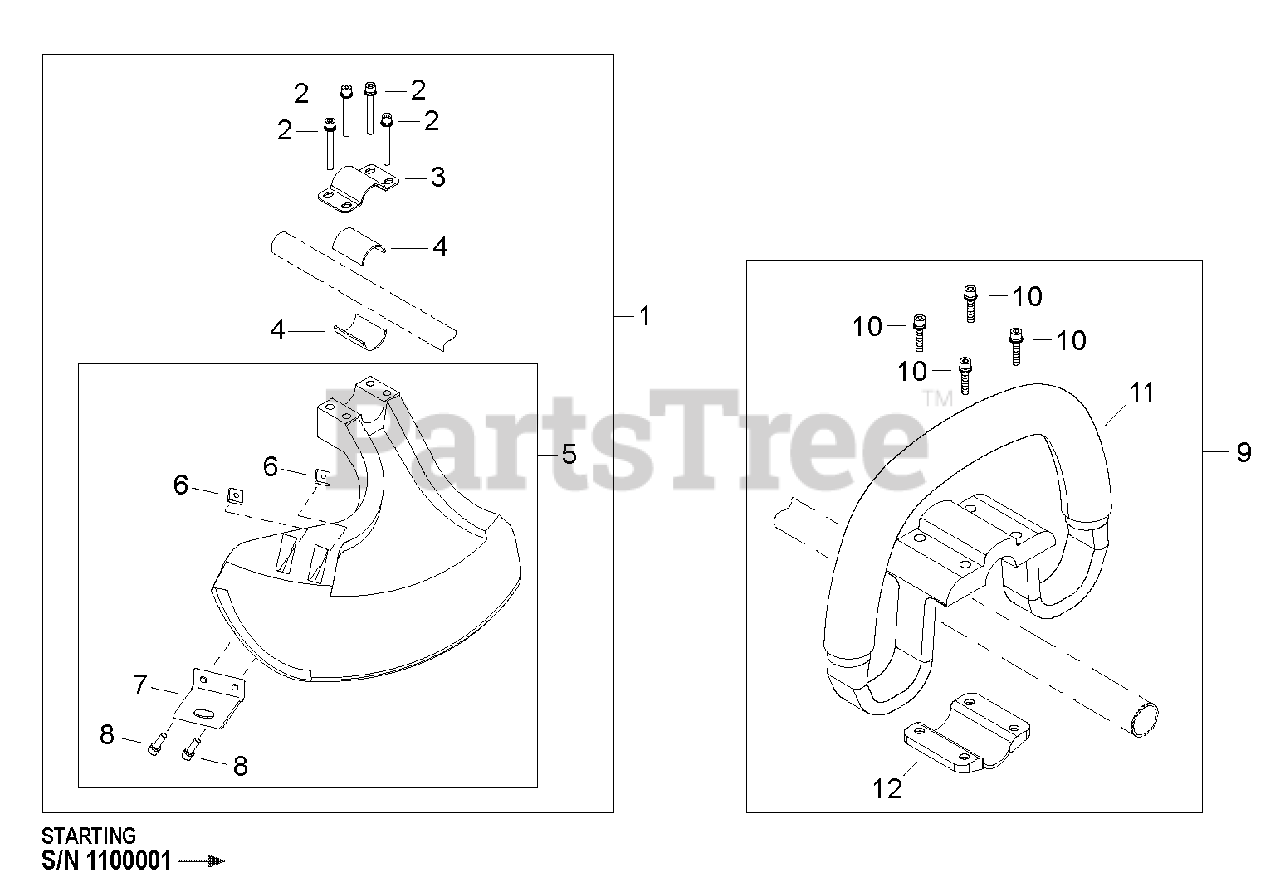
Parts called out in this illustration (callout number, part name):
1	DEBRIS SHIELD KIT
2	BOLT M5×45
3	CLAMP, UPPER
4	SPACER
5	DEBRIS SHIELD ASSY
6	NUT M5
7	CUTTER
8	BOLT M5×16
9	HANDLE ASSY - SUPPORT
10	BOLT M5×25
11	HANDLE
12	BRACKET, MOUNTING
